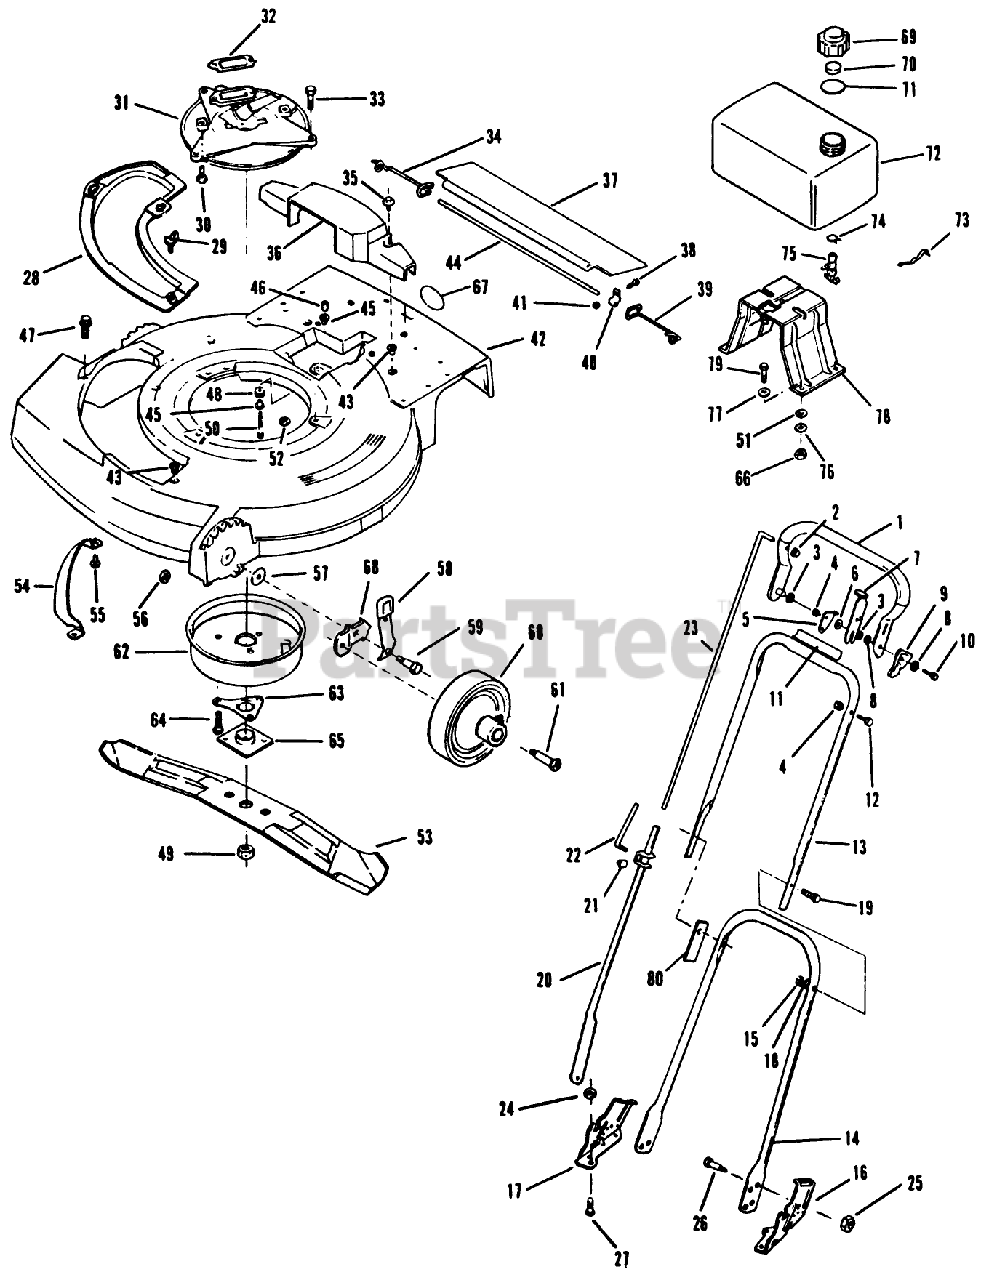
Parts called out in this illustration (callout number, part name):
3	WASHER M
4	LOCKNUT E
5	HANDLE STOP
7	LEVER LOCKOUT
10	BOLT PIONEER
12	SCREW-HANDLE STOP
14	Handle Bottom
15	LOCKNUT E
18	WASHER-CURVED
23	ROD CONTROL
24	NUT-LOCK F
25	NUT-JAM, LOCKING
29	WING SCREW LAWRE
30	SCREW V
34	SPRING;TRAILING SHIELD RH
35	SCREW SEMS TRM HEX HD
36	COVER
39	SPRIG T/SHLD ASOC
40	CLAMP ROD KMC
41	LOCKNUT E
44	ROD 21" ADVANCE
45	SPACER ECK PRES
48	GROMMET
49	NUT-BLADE
52	NUT-LOCK F
54	BAR-TOE
56	LOCKNUT
60	WHEEL & TIRE ASSY
61	BOLT-SHOULDER
62	MUFFLER COVER F
63	SUPPORT F
65	PLATE AND COLLAR ASM
66	LOCKNUT E
70	BAFFLE - FOAM SM
71	GASKET S
74	CLAMP - HOSE S
75	VALVE&SCREEN SM
79	BOLT PIONEER
